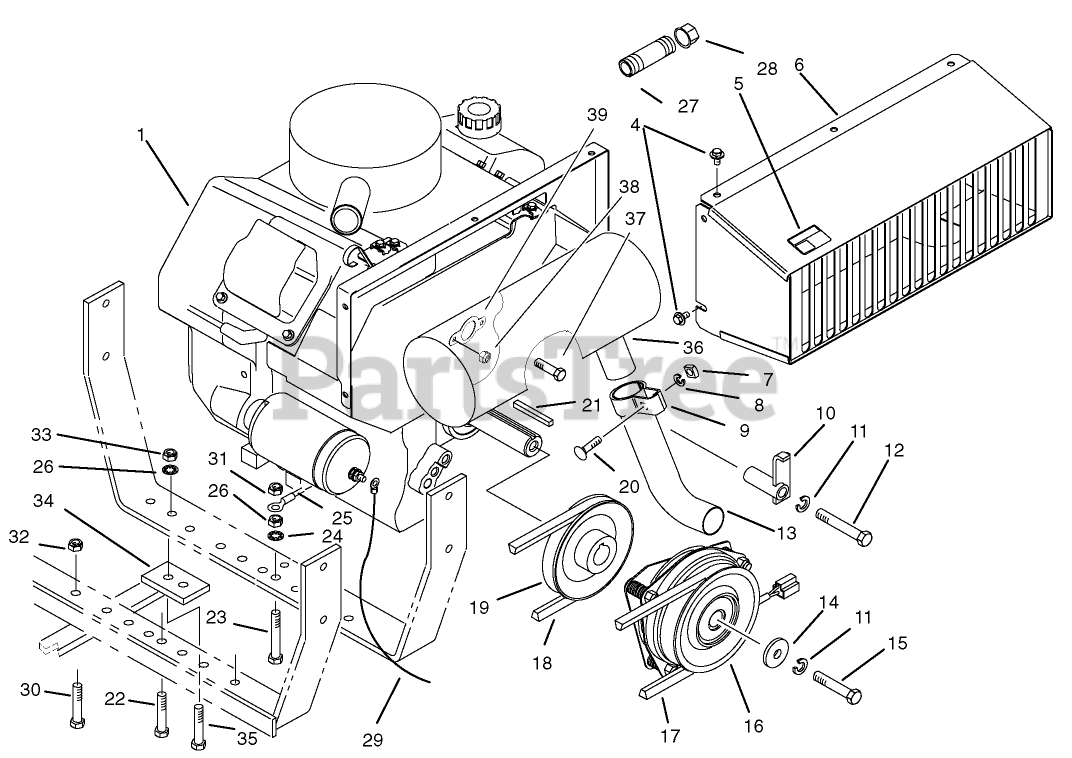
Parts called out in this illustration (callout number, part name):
1	Engine-Kohler 20 HP Model CH20QS PS 64556
4	SCREW
5	DECAL-SURFACE, HOT
6	Duct-Engine
7	NUT-HEX
8	WASHER-LOCK
9	Assembly-Clamp (Incl. Ref. #7, 8 & 20)
10	Anchor Bracket
11	WASHER-LOCK
12	SCREW-HH
13	EXHAUST PIPE
14	WASHER-CLUTCH
15	SCREW-HH
16	BRAKE CLUTCH ASM
17	V-BELT, JACKSHAFT
18	V-BELT, TRACTION
19	ENGINE PULLEY
20	SCREW-CARR
22	SCREW-HH
23	SCREW-HH
24	WASHER-LOCK, INTERNAL
25	WIRE ASM (NEGATIVE)
26	NUT-LOCK, NI
27	NIPPLE
28	CAP-PIPE
29	POSITIVE WIRE ASM
30	SCREW-HH
31	NUT-HHF, WHIZ
32	NUT-HF
33	WASHER-FLAT
34	Guard-Tank
35	SCREW-HH
36	Muffler
37	SCREW-HHF
38	Nut-Lock
39	GASKET-EXHAUST
